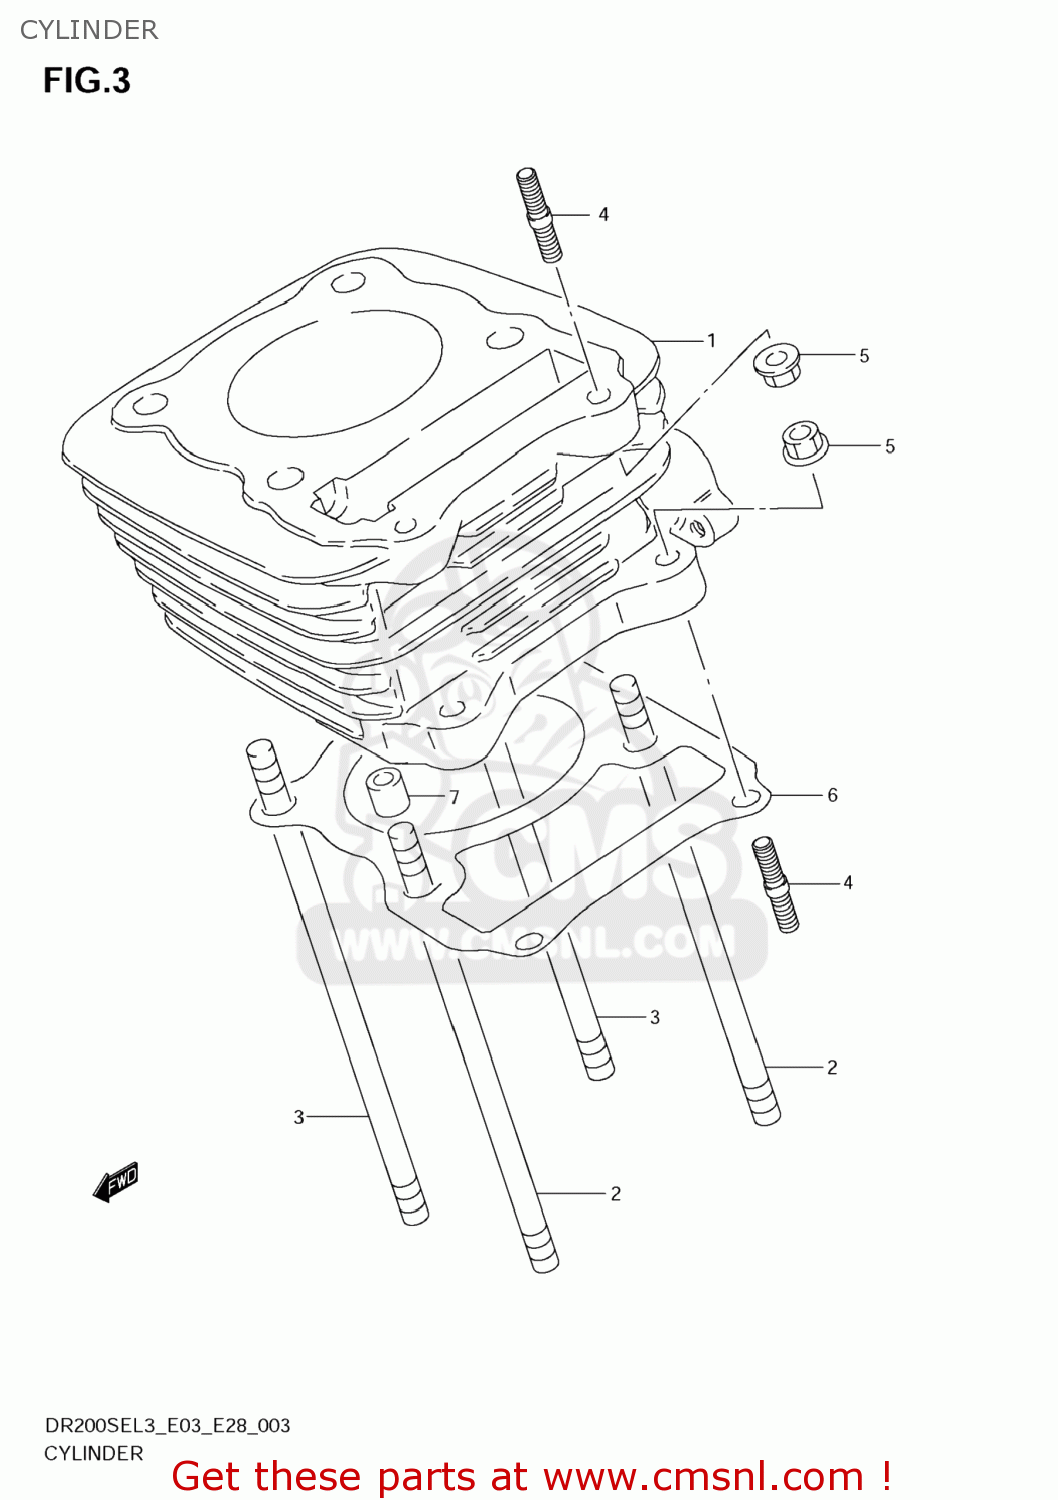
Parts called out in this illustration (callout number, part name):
1	CYLINDER
2	BOLT,STUD
3	BOLT,STUD(8X167)
4	BOLT,STUD
5	NUT
6	GASKET,CYLINDER (NAS)
7	PIN
